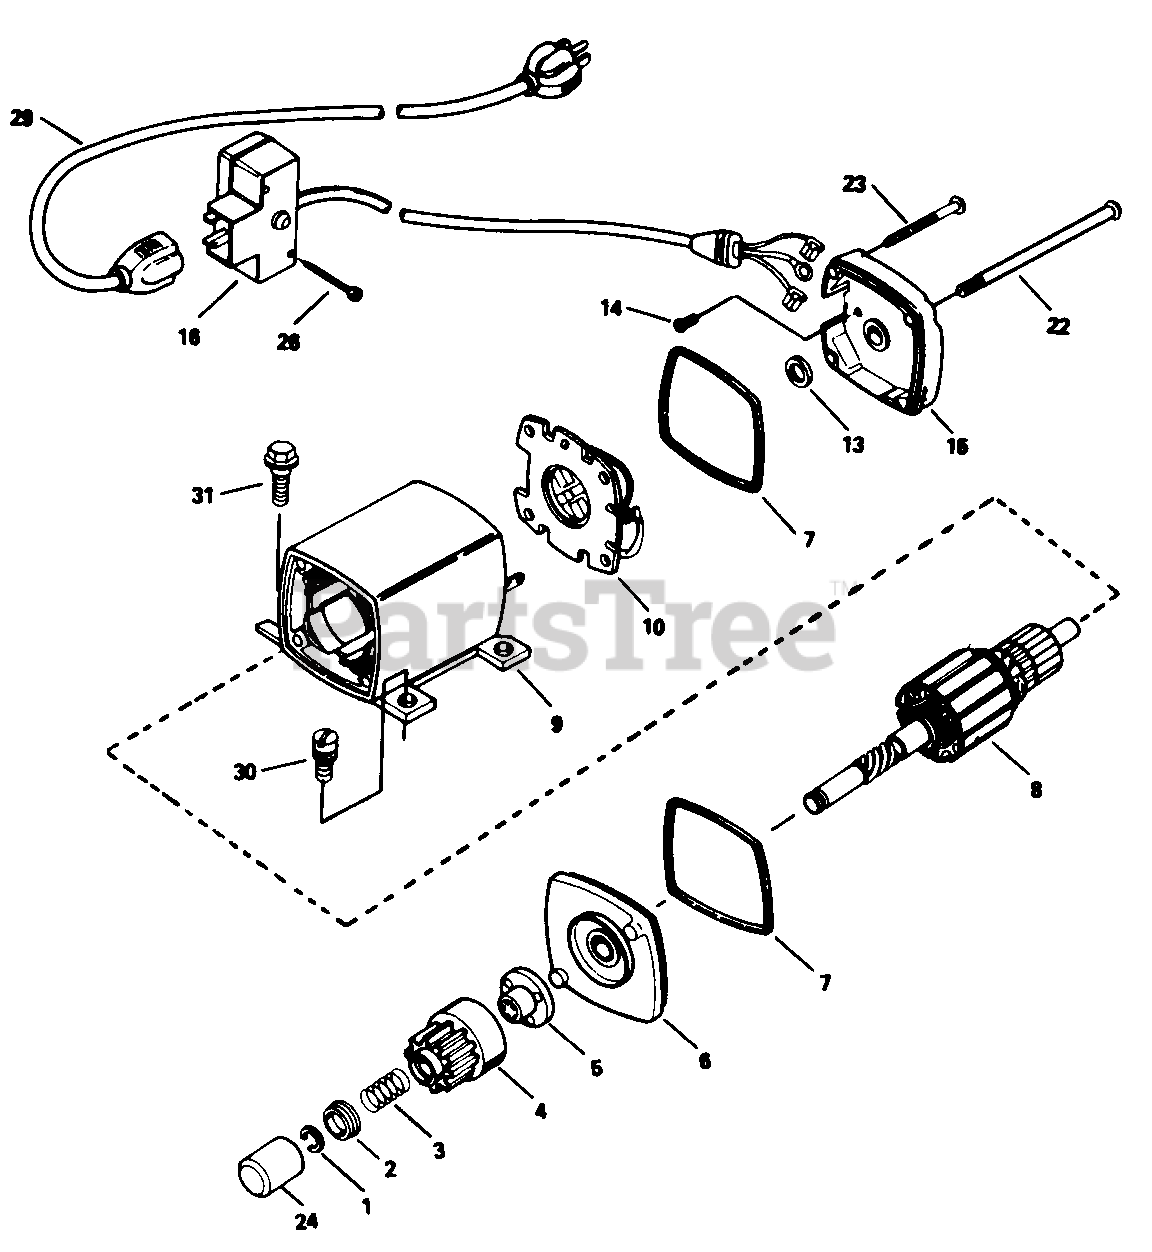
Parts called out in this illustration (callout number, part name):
1	Ring, Retainer
2	Retainer, Spring
3	Spring, Anti-drift
5	Nut, Engaging
6	Cap Ass'y., Drive End
9	Housing Ass'y.
10	Card Ass'y., Brush
13	Washer, Thrust
14	Screw, Ground
15	Cap Ass'y., Commutator End
16	Box Ass'y., Switch
22	Bolt, Case
23	Screw, Grounding
24	Cover, Dust
26	Screw, Hex Hd. Self-Tap, 6-32 x 2-1/2
29	Cord, Extension (10'6")
30	Screw, Fil. Hd. Sems, 1/4-20 x 9/1 6
31	Screw, Hex Hd. Shoulder, 1/4-20 x 1 /2
